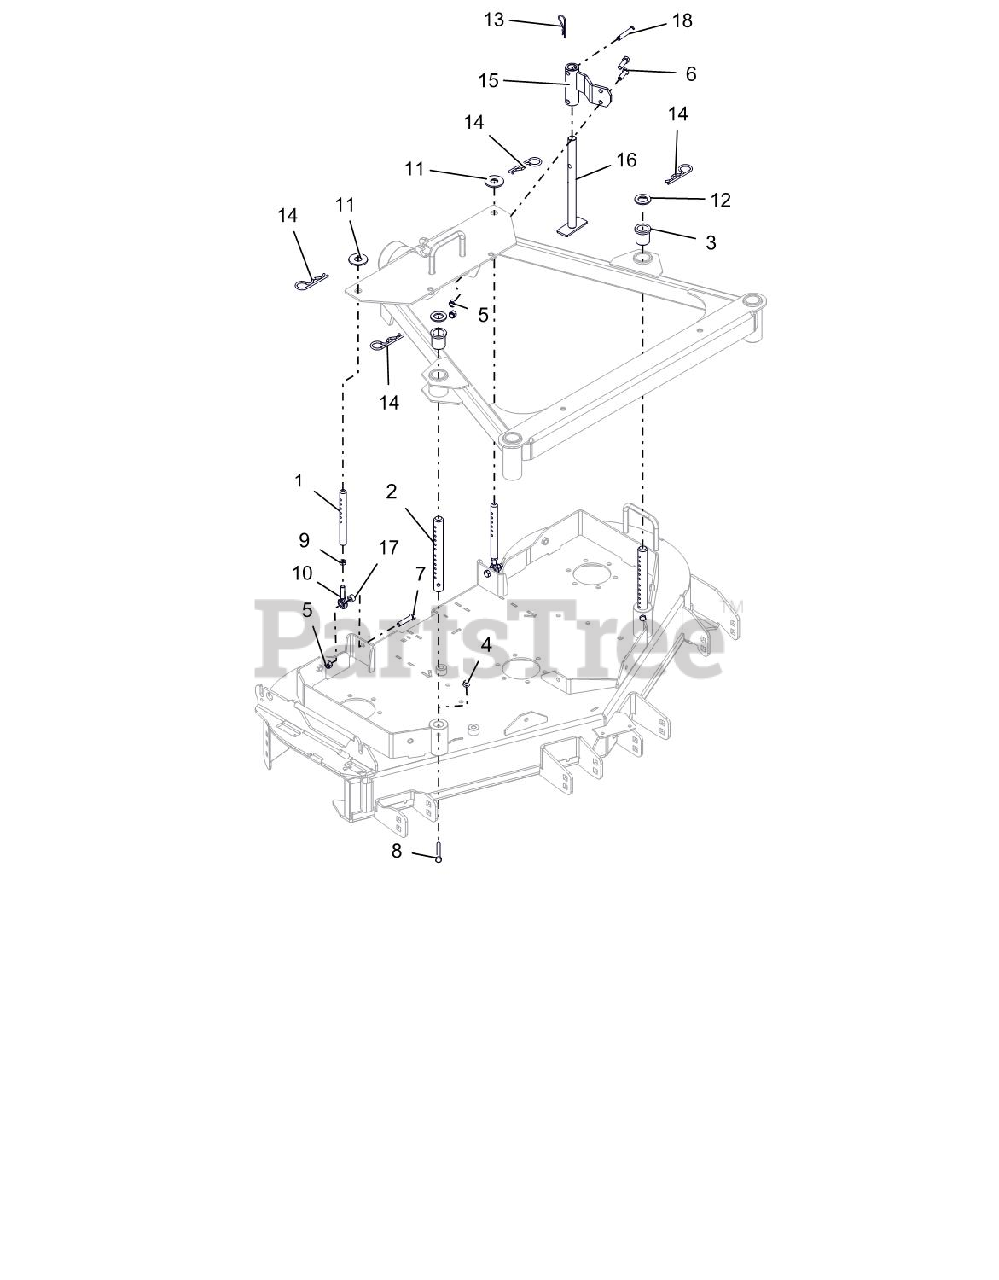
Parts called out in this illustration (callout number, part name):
1	PIN, REAR HOC
2	PIN, FRONT HOC
3	BSHG-FLG 1.00X1.25X1.50X1.50
4	NUT,SPNLK-FLG .312-18 ZC120
5	NUT,NYL .38-16 G5 ZCC
6	BLT, HEX .38-16X1.25 G5 ZCC
7	BLT, HEX .38-16X1.75 G5ZC120
8	BLT-HEX .31-18X2.50 G8ZC120
9	NUT, HEX-JAM .375-24 ZC120
10	ROD END, 3/8 RH
11	WSHR,FLT .688X1.75X.134 ZCC
12	WSHR-FL-STL .875X1.5X.119
13	PIN, HAIR-#7 .094X2.31 ZC120
14	PIN, HAIR-.17X.68X3.50 ZC120
15	BRKT, STAND (RED)
16	WLDT, STAND
17	BSHG-SLV .377X.624X.370
18	PIN, CLEVIS
